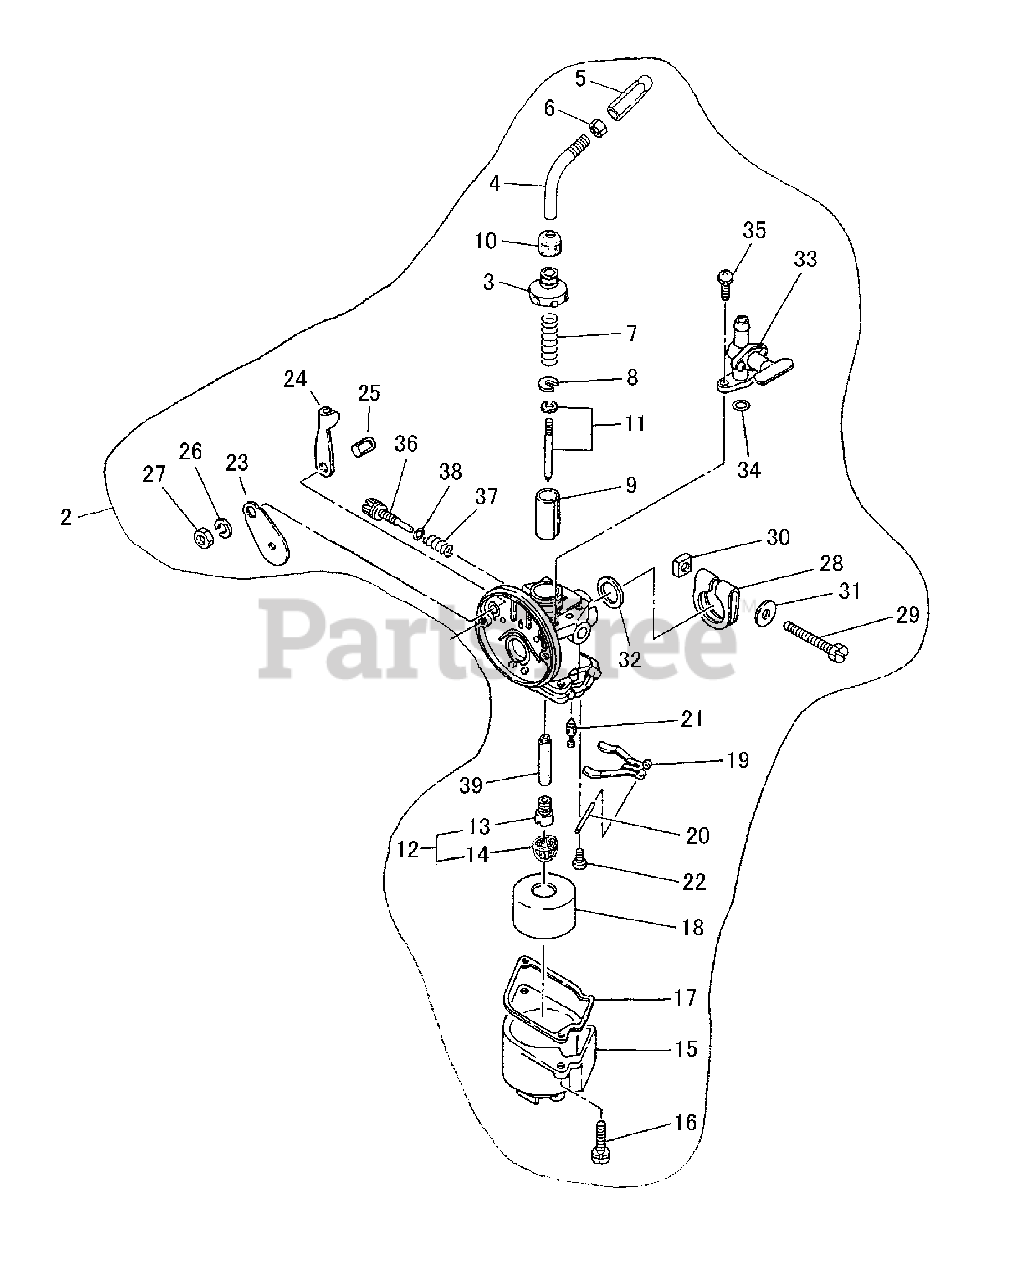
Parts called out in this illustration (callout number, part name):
2	CARBURETOR
3	CAP, CARBURETOR
4	PIPE, CABLE ADJUSTER(4 pieces ×2 M)
5	ADJUSTER, CABLE
6	NUT, LOCK
7	SPRING, THROTTLE
8	WASHER, SPRING SUPPORT
9	VALVE, THROTTLE
10	CAP, DUST
11	NEEDLE, JET
12	JET ASSY, MAIN
13	JET, MAIN
14	FILTER, FUEL
15	CHAMBER, FLOAT
17	GASKET, FLOAT CHAMBER
18	FLOAT
19	HINGE, FLOAT
20	PIN, HINGE
21	VALVE, INLET NEEDLE
22	SCREW
23	PLATE, CHOKE
24	LEVER, CHOKE
25	BOLT
26	WASHER, SPRING
27	NUT, LOCK
28	CLAMP
29	BOLT
31	WASHER
32	GASKET, MOUNTING
33	COCK, FUEL
34	O-RING
35	SCREW
36	SCREW, SLOW STOP
37	SPRING
38	O-RING
39	NOZZLE
